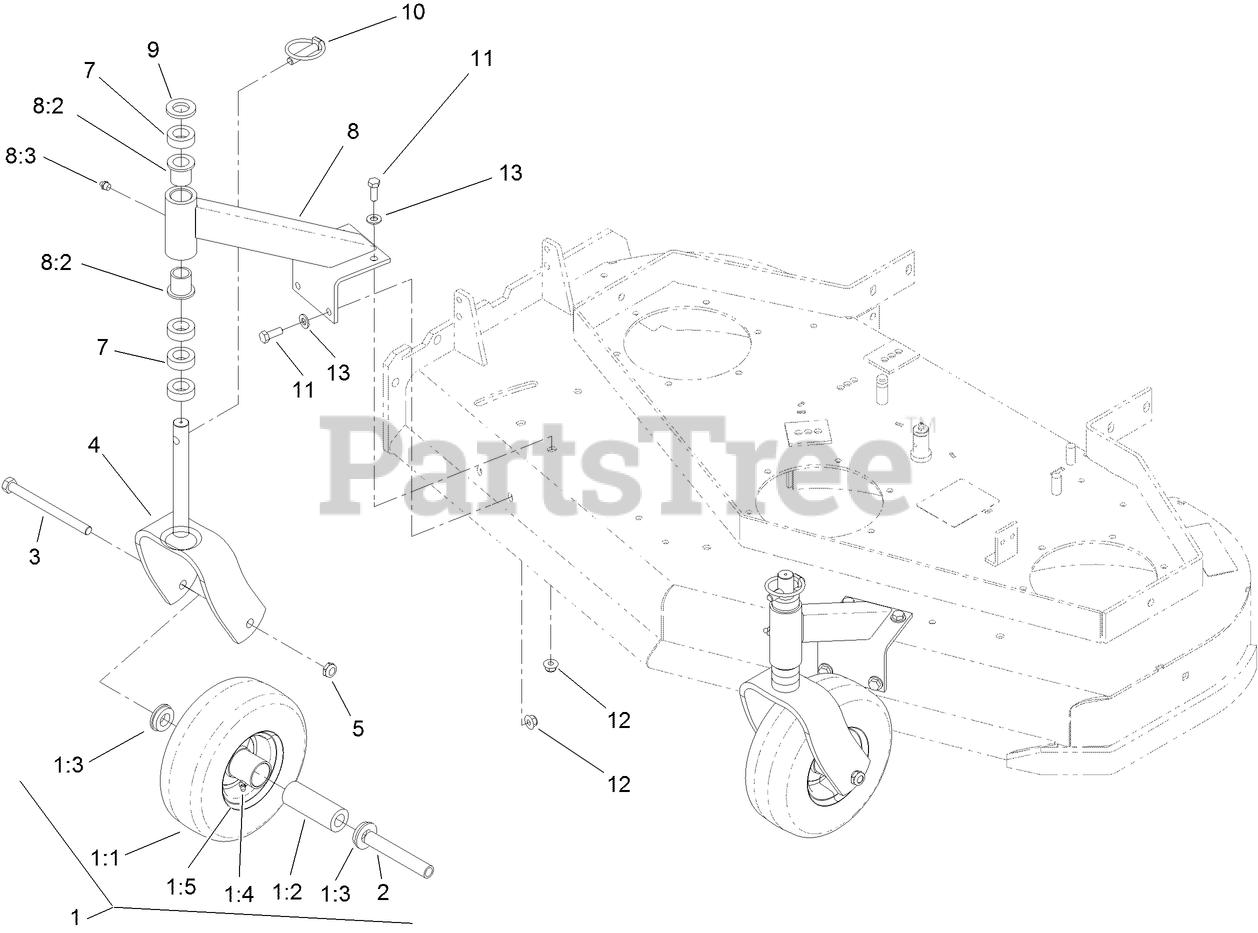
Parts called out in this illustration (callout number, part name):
1	WHEEL AND TIRE ASM
1:1	TIRE
1:2	BEARING
1:3	BUSHING
1:4	FITTING-GREASE
1:5	WHEEL
2	SPACER
3	SCREW-HH
4	FORK-CASTER
5	NUT-HEX
7	SPACER-CASTER
8	SUPPORT ASM
8:2	BEARING-FLANGED
8:3	FITTING-GREASE
9	WASHER-FLAT
11	SCREW-HH
12	NUT-HF, NI
13	WASHER-FLAT
